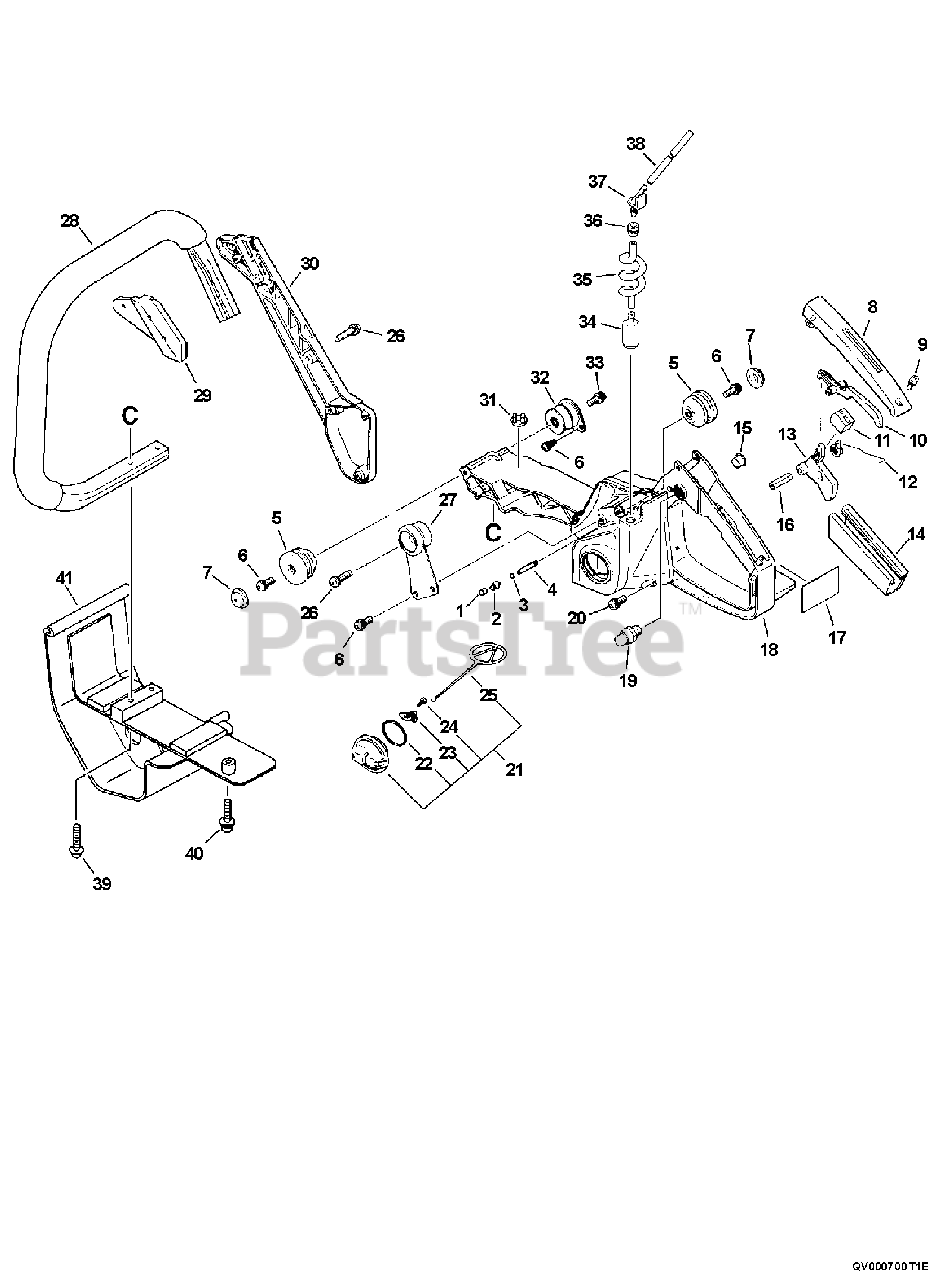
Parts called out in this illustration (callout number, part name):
1	VENT, FUEL TANK
2	COVER, VENT
3	CLIP - 5.5
4	PIPE - 3X5X55 -- BLACK
6	SCREW - 5X14
7	CAP, CUSHION
8	COVER, HANDLE
9	SCREW - 4X14
10	LEVER, TRIGGER LOCKOUT
12	SPRING, TRIGGER
13	TRIGGER, THROTTLE
14	GRIP, HANDLE
16	PIN - SPRING -- 5X25
17	LABEL - CAUTION
18	HANDLE - REAR
19	LATCH, THROTTLE
20	SCREW - 4X14
21	CAP ASSY
22	O-RING - 29
23	RETAINER
24	SCREW - 3X8
25	CONNECTOR, CAP
26	SCREW - 5X20
28	HANDLE - FRONT
29	BRACKET, HANDLE
30	BRACKET, HANDLE
33	SCREW - 4X10
34	FILTER, FUEL
35	PIPE - BLACK
36	GROMMET
37	CONNECTOR, PIPE
38	PIPE - 3X6X120 -- BLACK
39	SCREW - 5X30
40	SCREW - 5X25
